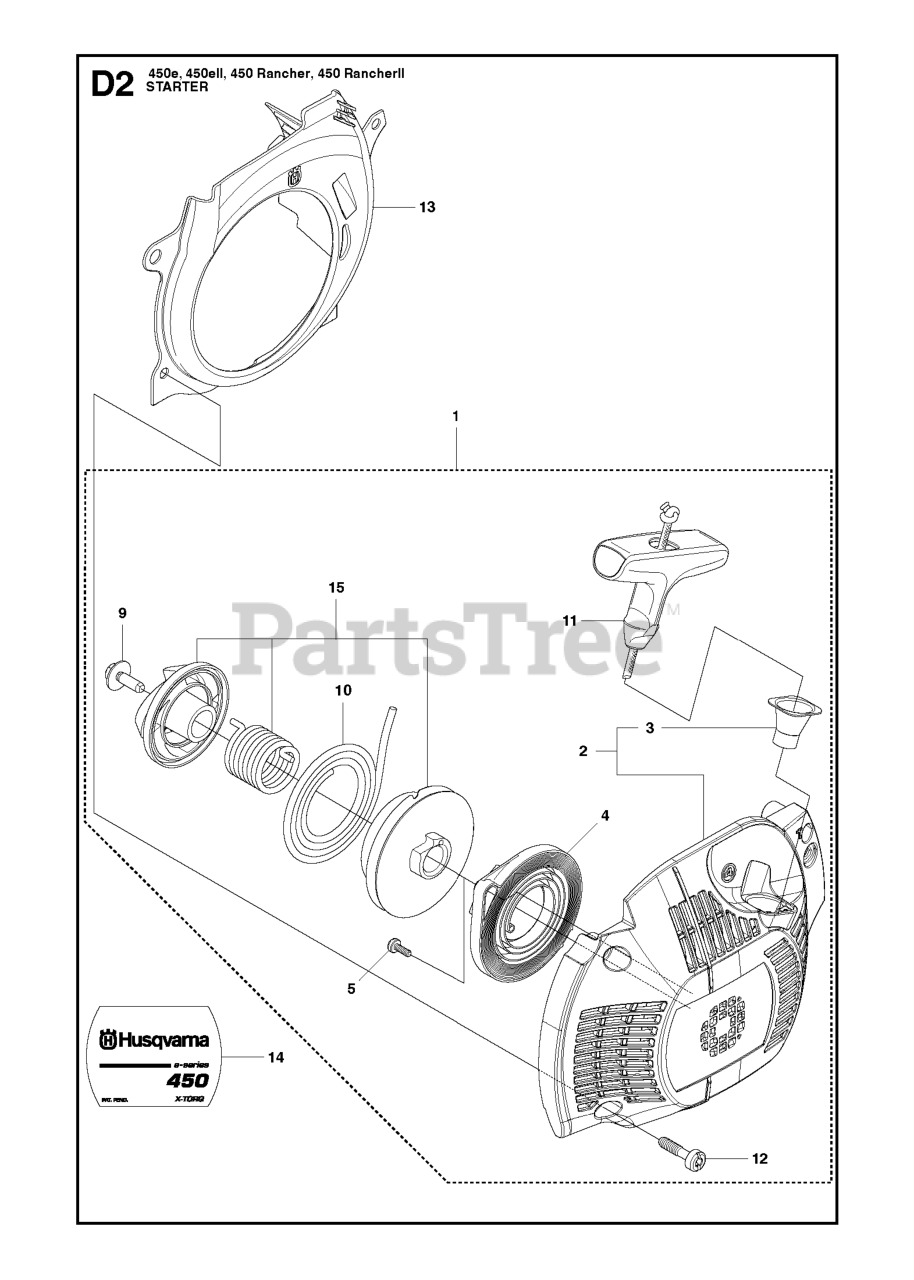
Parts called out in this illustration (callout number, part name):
1	STARTER ASSY
4	SPRING CASSETTE ASSY
10	STARTER ROPE
13	COOLING AIR CONDUCTOR
14	LABEL
14	LABEL STARTER 450 RANCHER
15	STARTER PULLEY KIT
